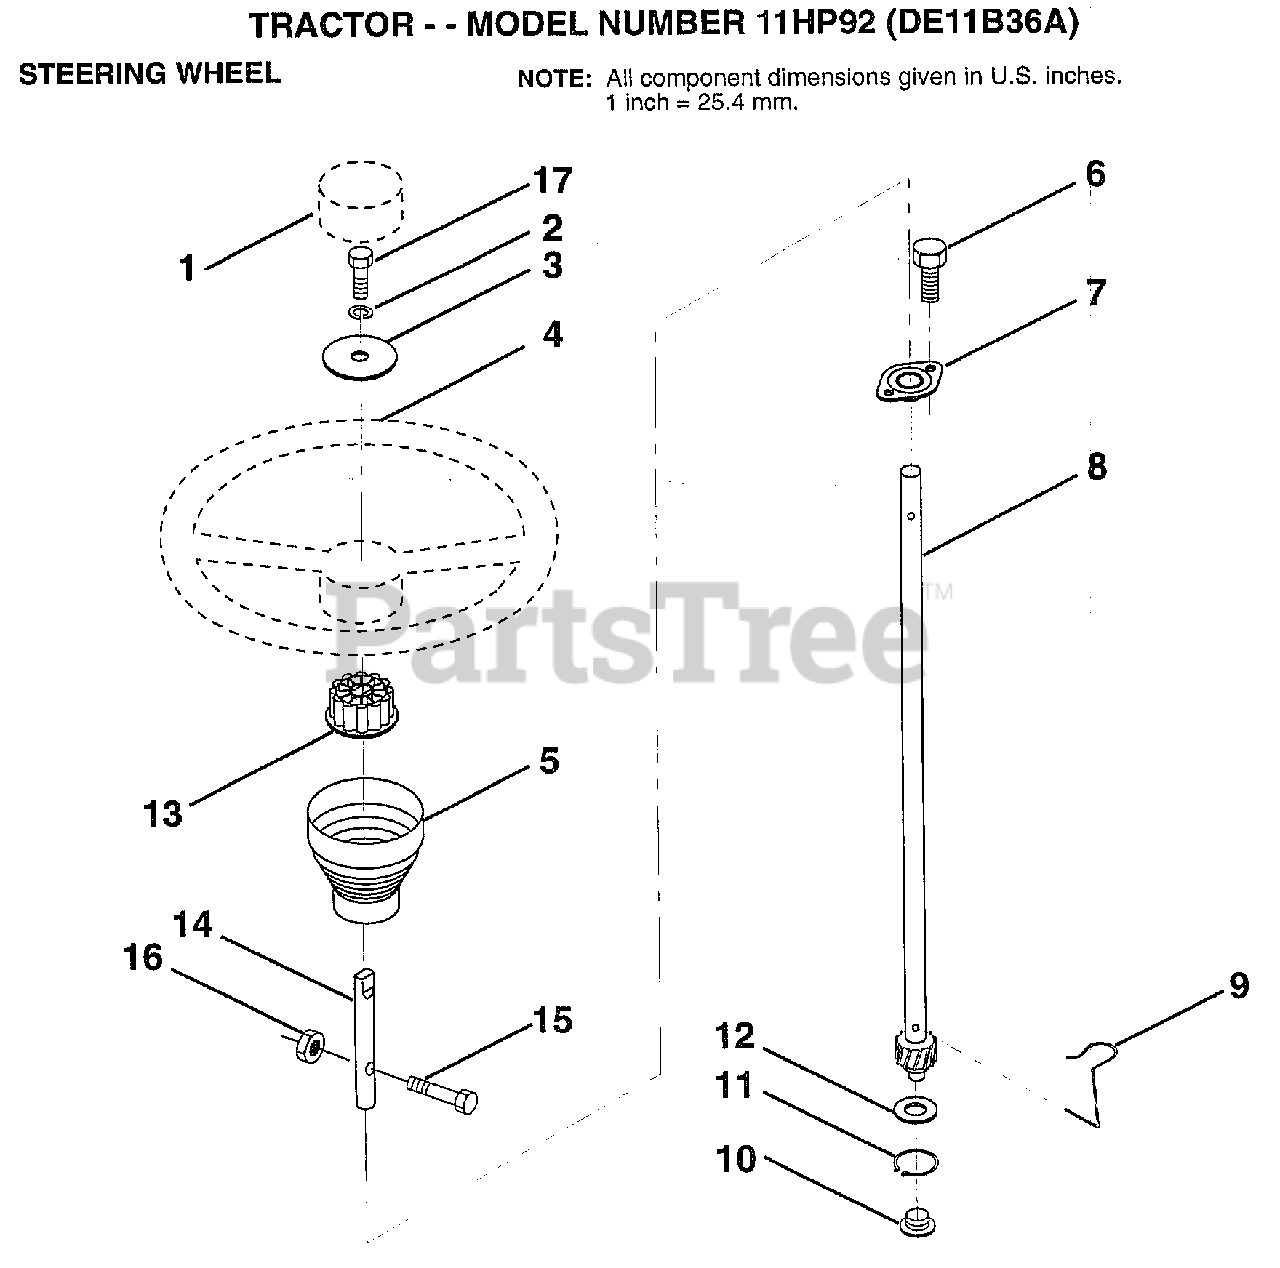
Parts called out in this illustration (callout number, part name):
1	CAP WHEEL STEER
2	LOCKWASHER
3	WASHER T
5	SLEEVE STEERING
6	"SCREW-TT,10-32 FL"
7	BUSHING.STR.623
8	SHAFT.STEERING.LR
9	STEERING CLIP
10	BUSHING STEER LWR
11	RING
12	WASHER LT
13	ADAPTER LT
14	EXT SHAFT STEERIN
15	BOLT
16	NUT
17	BOLT
